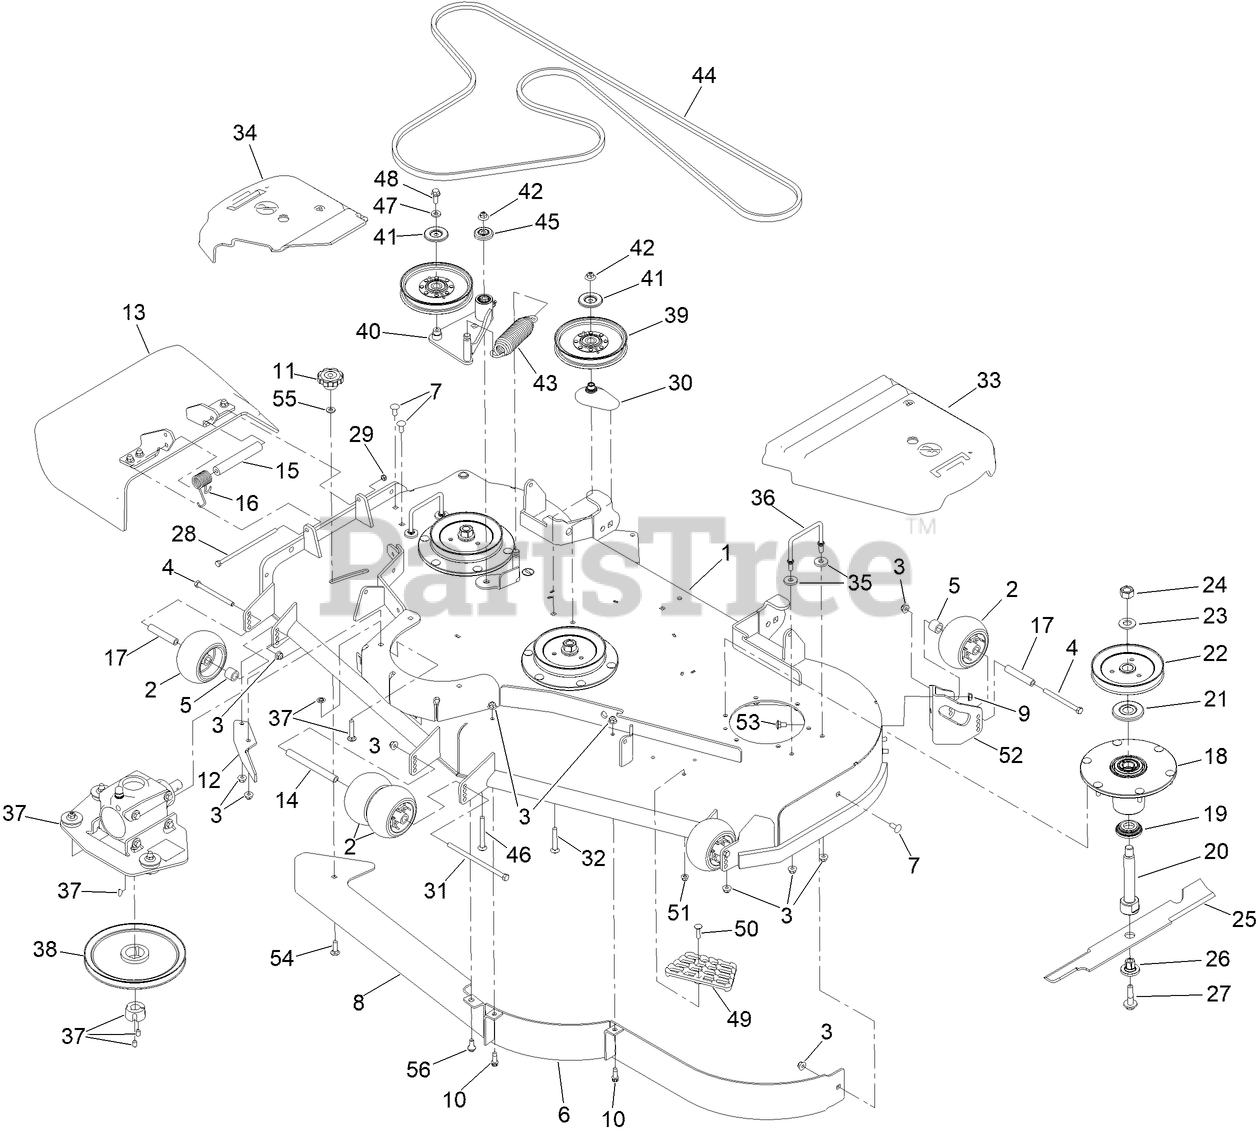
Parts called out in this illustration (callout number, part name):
1	DECK ASM-60TF
2	ROLLER-SCALP, ANTI
3	NUT-HF, NI
4	SCREW-HH
5	TUBE-SPACER
7	SCREW-CARR
8	PLATE-BAFFLE
9	NUT-HHF, WHIZ
12	BAFFLE-DISCHARGE
13	RUBBER DEFLECTOR ASM
14	SPACER-WHEEL
15	SPACER
16	SPRING-TORSION
17	TUBE-SPANNER
18	SPINDLE ASM
19	GUARD-BOTTOM
20	SHAFT-SPINDLE
21	GUARD-BEARING, TOP
22	SHEAVE-BLADE DRIVE 6.50
23	WASHER
24	NUT-HEX
26	BUSHING-HEX
27	SCREW-SEMS
28	SCREW-HH
29	NUT-LOCK, NI
30	SPACER-PULLEY
31	SCREW-HH
32	SCREW-CARR
33	COVER-BELT, LH
34	BELTSHIELD-RT, 60
35	WASHER
36	WIREFORM-COVER
37	GEARBOX ASM
38	PULLEY
39	IDLER-PULLEY
40	IDLER ARM ASM
41	SHIELD-DUST
42	NUT-FLANGE, NI
43	SPRING-EXTENSION
44	BELT-V
45	GUARD-TOP
46	BOLT-SHOULDER, CARRIAGE
47	SPACER
48	SCREW-HHF
49	STEP-DECK
50	SCREW-CARR
51	NUT-HF, NI
52	MOUNT-WHEEL, LH
53	SCREW-CARR
54	BOLT-CARR
55	WASHER-HARDENED
56	BOLT-SHOULDER
